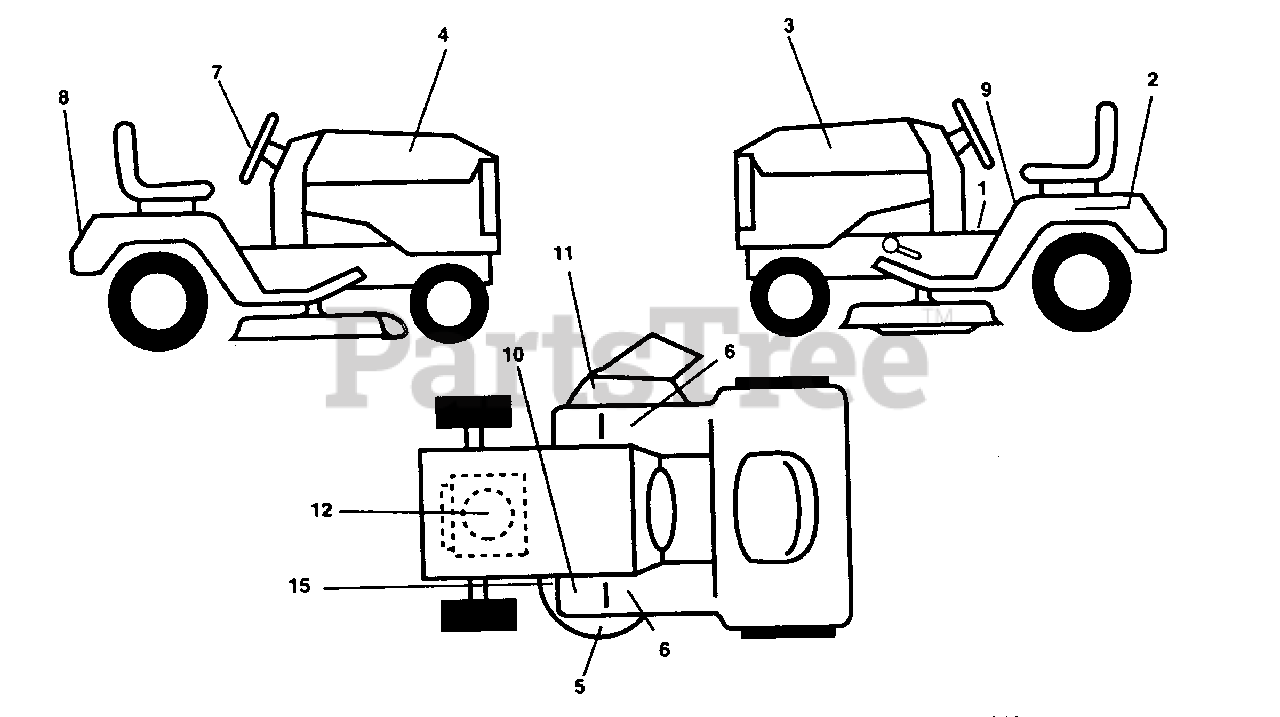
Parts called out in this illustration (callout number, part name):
1	Decal Instruction Dash Eng/fr
2	Decal Battery Dan/Poi P/L Symbols
3	Decal Hood LH
4	Decal Hood RH
5	Decal Enviro Deck Yellow
6	Pad Footrest Ribbed
7	Decal Insert Strg Whl
8	Decal Fender Logo
9	Decal Caution Fender Eng/fr
10	Decal Clutch/brake Eng/fr
11	Decal Warning Multi-Language
12	Decal Engine B&S 14.5 ICQ OHV
15	Decal V-Belt Schematic
